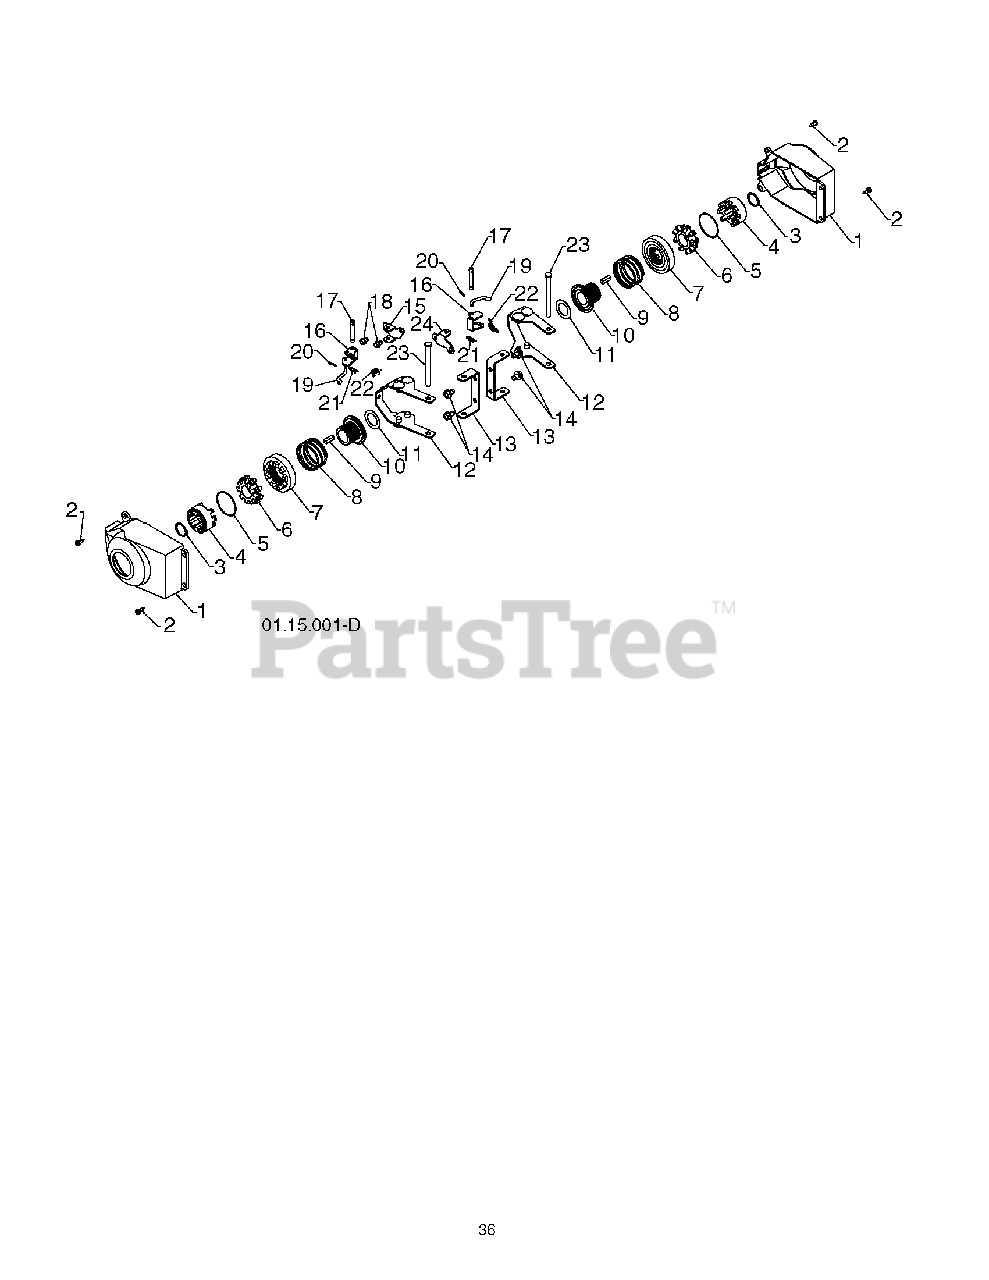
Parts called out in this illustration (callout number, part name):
1	COVER, POWER STEERING
2	SCREW, HEX HEAD, TAPPING
4	DRIVER WHEEL
5	RING, WIRE RETAINER
6	LOBE WHEEL
7	SLIDE.CLUTCH
8	SPRING, CLUTCH SLIDE
9	KEY, SQUARE 1/4 X .875
10	LOBE.AXLE
11	WASHER 1.00
12	YOKE.WELDMENT.STEER.BLACK
13	BRACKET.STEER.PNT.BLACK
14	SCREW LT
17	PIN, STEERING BELLCRANK
18	SCREW 1/4X20
19	LINK.STEER.YOKE
20	RETAINER CLIP
21	RETAINER CLIP PM
22	SPRING LATCH
23	PIN, STEERING LEVER
